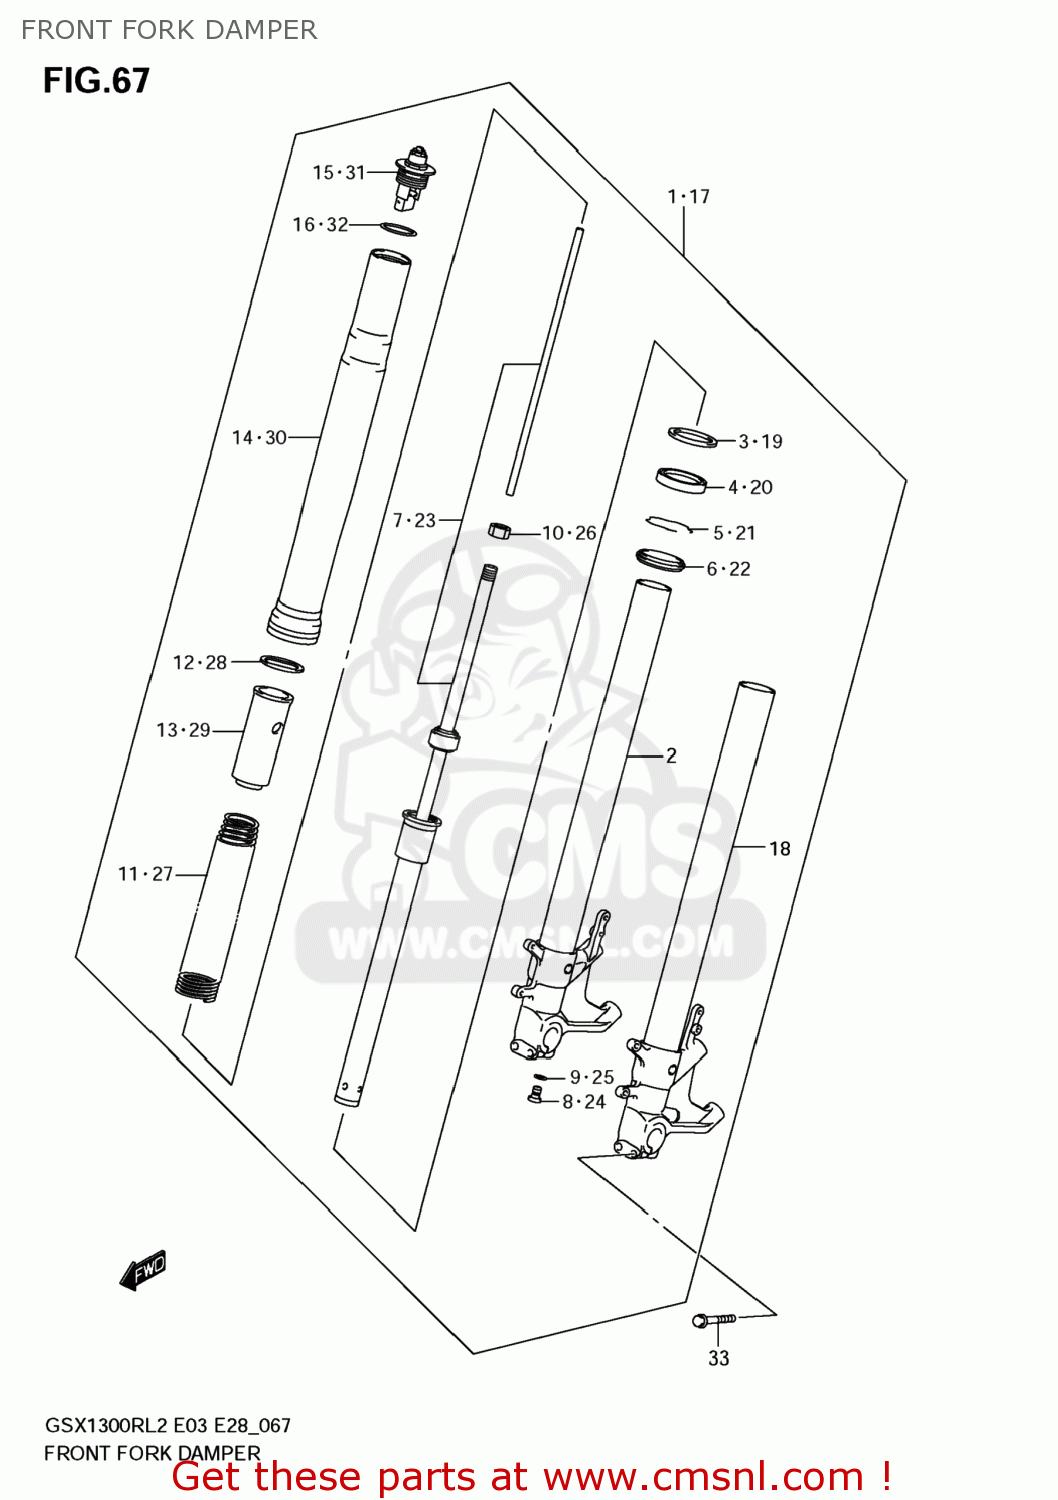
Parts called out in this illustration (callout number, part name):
1	DAMPER ASSY,FR FORK,R
2	TUBE,INNER,R
3	WASHER
4	SEAL,OIL
5	RING,STOPPER
6	SEAL,DUST
7	CYLINDER
8	BOLT
9	GASKET (NAS)
10	NUT,ROD
11	SPRING,FR
12	GUIDE,SPRING
13	SPACER,SPRING
14	TUBE,OUTER
15	CAP,FR FORK
16	O RING
17	DAMPER ASSY,FR FORK,L
18	TUBE,INNER,L
19	WASHER
20	SEAL,OIL
21	RING,STOPPER
22	SEAL,DUST
23	CYLINDER
24	BOLT
25	GASKET (NAS)
26	NUT,ROD
27	SPRING,FR
28	GUIDE,SPRING
29	SPACER,SPRING
30	TUBE,OUTER
31	CAP,FR FORK
32	O RING
33	BOLT
